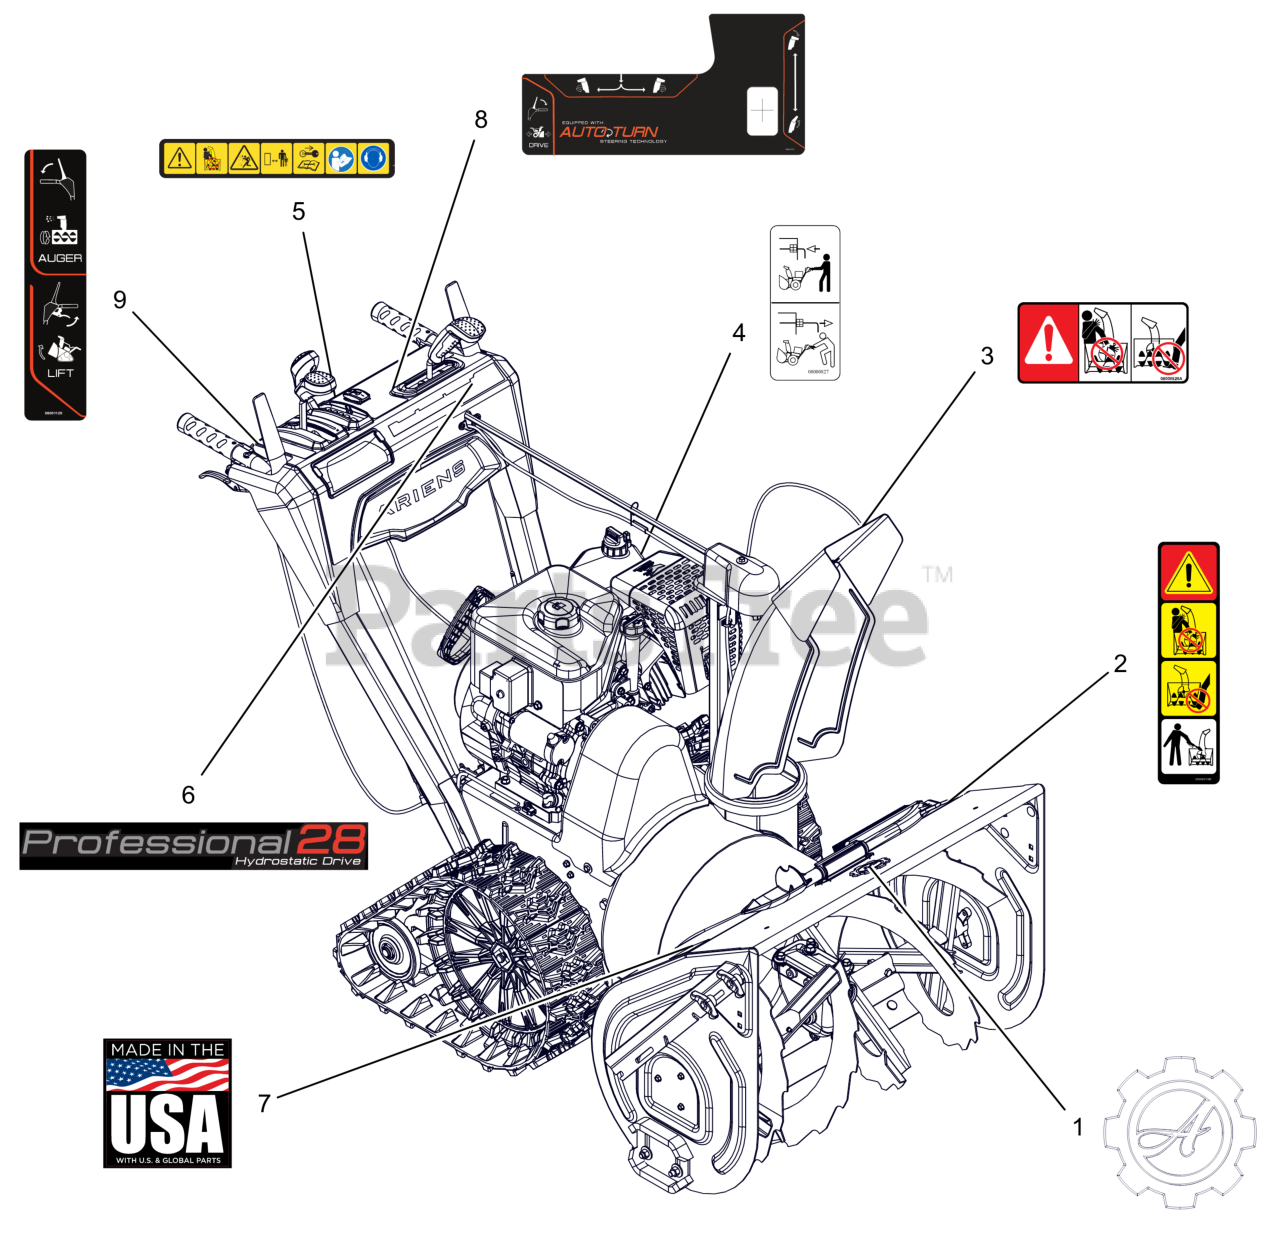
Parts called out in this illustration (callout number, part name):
1	DECAL, ARIENS-GEAR BADGE -THK
2	DECAL, DANGER - ROTATING PARTS
3	DECAL, DANGER
4	DECAL, BYPASS
5	DECAL,DASH - SAFETY
6	DECAL, DASH - PRO HYDRO 28
7	DECAL, MADE IN USA
8	DECAL,CONTROL-LG QT2
9	DECAL,CONTROL-RH TRACK
